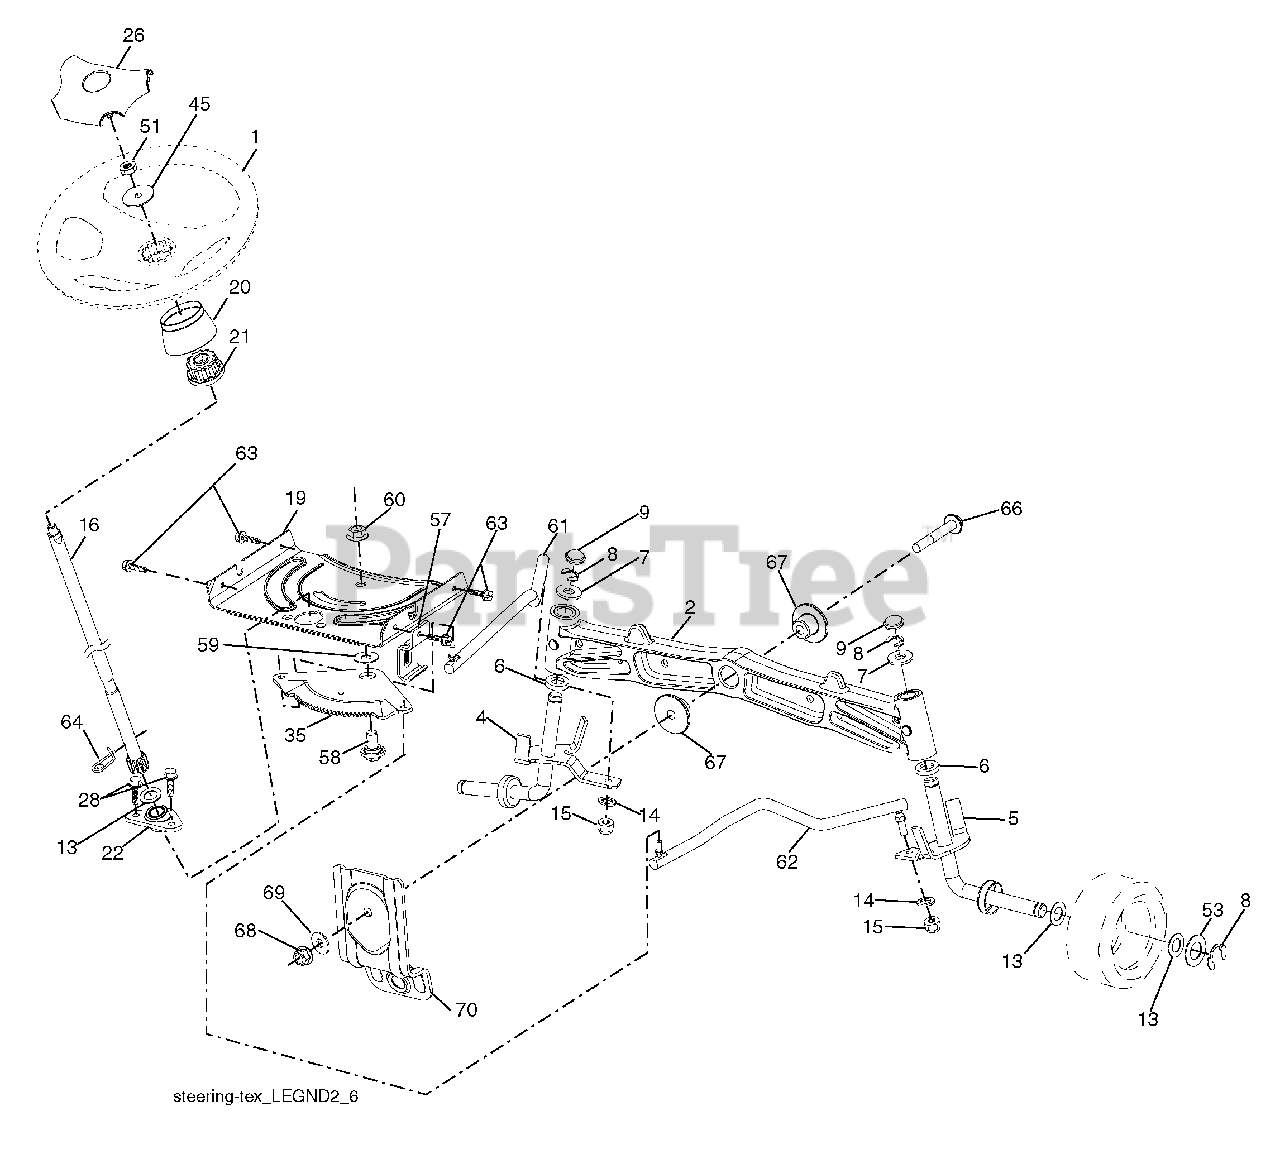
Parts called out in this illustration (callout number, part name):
1	Wheel, Steering
2	Axle Asm. Front
4	Spindle Asm. LH
5	Spindle Asm. RH
6	Bearing, Race Thrust Harden
7	Washer 25/32 x 1-5/8 x 16 Ga.
8	Ring, Clip #T5304-75
9	Cap, Spindle
13	Washer 25/32 x 1-1/4 x 16 Ga.
14	Washer, Lock Hvy. Hlcl. Spr. 3/8
15	Nut, Crown Lock 3/8-24 unf
16	Shaft Steering
19	Plate Steering
20	Boot, Steering
21	Adapter, Wheel Steering
22	Bushing, Strg. Blk.
26	Insert, Wheel Steering
28	Screw 3/8-16 x 3/4
35	Gear, Sector Plate
45	Washer 11/32 ID x 2-3/8 OD x 12 Ga.
51	Nut Hex Jam Toplock 1/2-20 unf
53	Washer Hardened .793 x 1.637 x .060
57	Bracket Upstop
58	Bolt Shoulder Sector Pivot CFM
59	Washer Thrust Sector Steering
60	Nut Flange Lock 5/8-11
61	Draglink LH
62	Draglink, RH
63	Screw 5/16-18 x 3/4
64	Retainer Clip Spring Steering
66	Bolt Hex Fghd. 7/16-14 x 3 Serr.
67	Bushing PM Front Axle
68	Nut Lock Flange 7/16-14 Gr. 5
69	Washer 1.5 x .505 x .118
70	Bracket Deck Susp. Front
